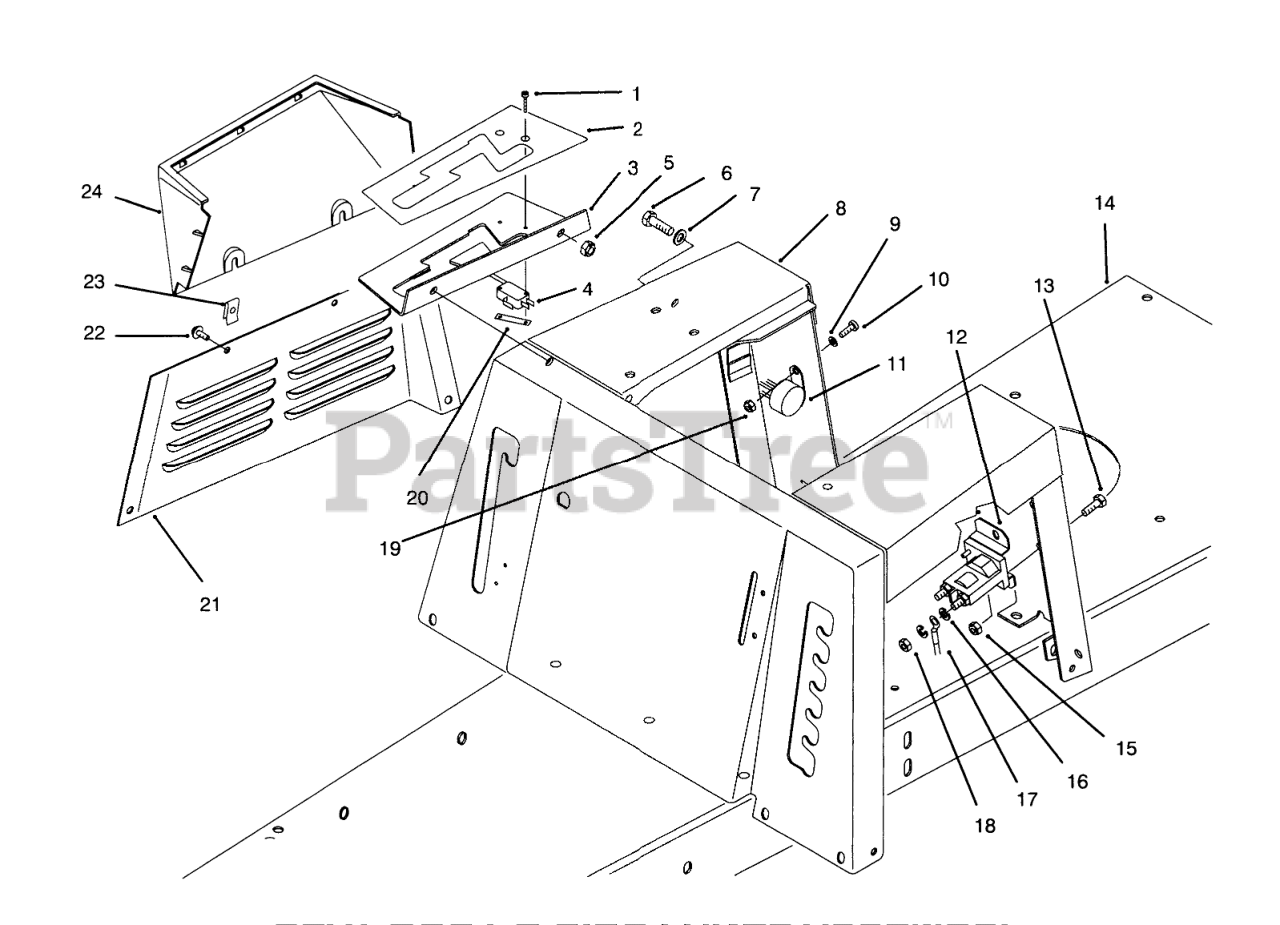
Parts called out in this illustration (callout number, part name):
1	SCREW-HH
2	DECAL - SHIFT PATTERN
3	Gate-Shift
4	SWITCH-MICRO
5	NUT-LOCK, NI
6	SCREW-HH
7	WASHER-PLAIN
8	Body W.A.-Seat Support
9	WASHER-FLAT
11	Module Interlock
12	SOLENOID
13	SCREW-HH
14	Frame
15	NUT-LOCK, NI
16	WASHER-LOCK
17	WIRE ASM
18	NUT-JAM
19	NUT-LOCK, NI
20	NUT-SPEED
21	Panel-Seat Base, R.H.
22	SCREW-HWH
23	NUT-CLIP,U
24	COVER-SHIFT GATE
